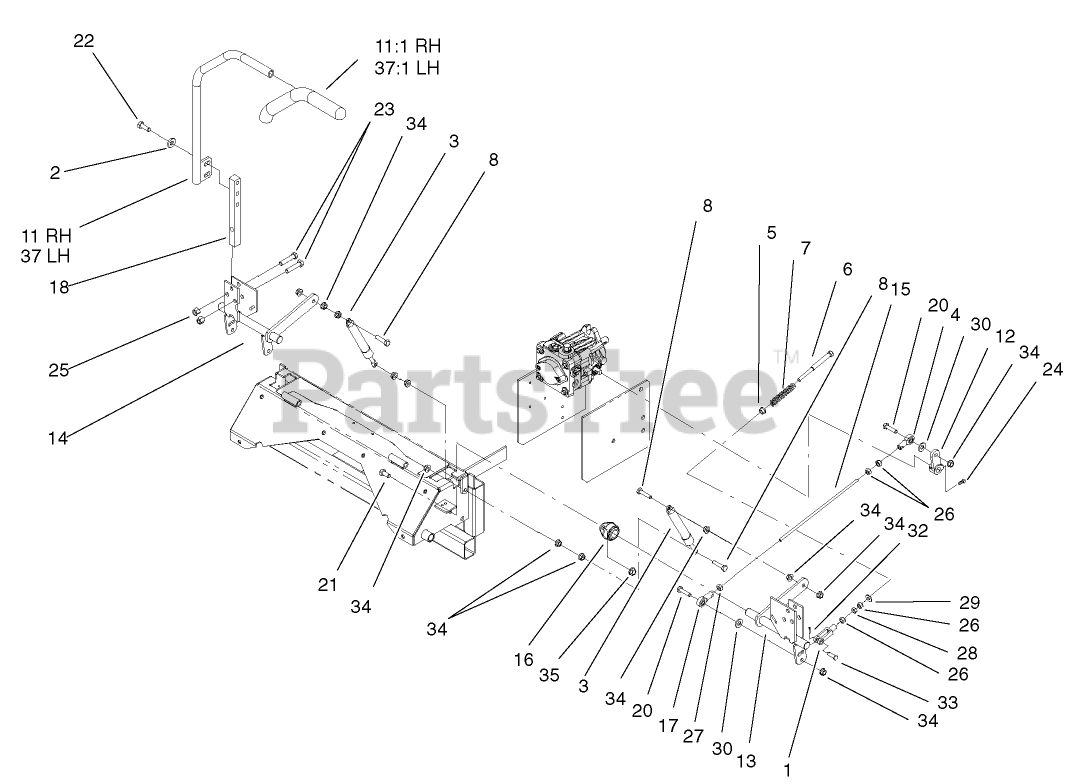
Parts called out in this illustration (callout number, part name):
1	YOKE-ADJUSTABLE
2	WASHER-BELLEVILLE
3	DAMPER-CONTROL
4	BALLJOINT-RH
5	BUSHING-FLANGED
6	BOLT-RETURN, NEUTRAL
7	SPRING-RETURN, NEUTRAL
8	SCREW-HH
11	RH LEVER ASM
11:1	GRIP-CONTROL, MOTION
12	ARM-CONTROL, PUMP
13	CONTROL-MOTION, LH
14	CONTROL-MOTION, RH
15	LINKAGE-PUMP/LEVER
16	BEARING-FLANGE, SIDE
17	BALLJOINT-LH
18	ARM-SHAFT, CONTROL
20	SCREW-HH
21	SCREW-HH
22	SCREW-HH
23	SCREW-HH
24	SCREW-SET
25	NUT-LOCK, NI
26	NUT-HEX
28	NUT-JAM
29	WASHER-FLAT
30	WASHER-FLAT
32	PIN-COTTER
33	PIN-CLEVIS
34	NUT-HF
35	NUT-HHF, WHIZ
37	LH LEVER ASM
37:1	GRIP-CONTROL, MOTION
